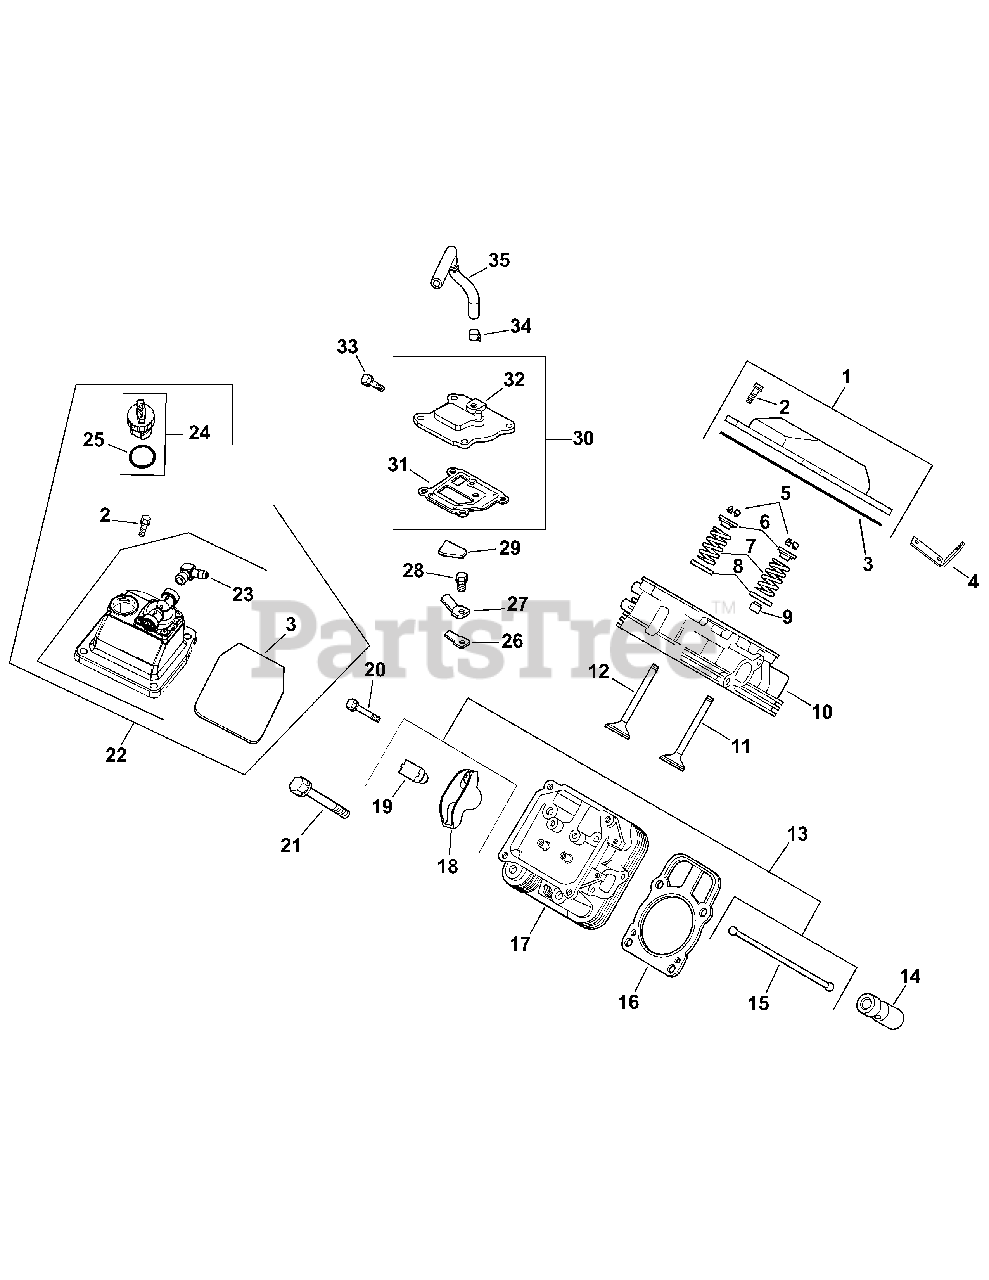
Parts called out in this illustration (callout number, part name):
1	Kit, valve cover - plain (Includes 2,3)
2	Screw, hex. flange M6x1.0x30 (4)
3	O-Ring, valve cover
4	Strap, lifting
5	Kit, retainer (4)
6	Cap, valve spring (4)
7	Spring, valve (4)
8	Retainer, spring (4)
9	Seal, valve stem (2)
10	Head assembly, #1 cylinder
11	Valve, intake (Std.) (2)
11	Valve, intake (.25) (2)
12	Valve, exhaust (Std.) (2)
12	Valve, exhaust (.25) (2)
13	Kit, valve train (Includes 15,18,19)
14	Lifter, valve (4)
15	Rod, push (4)
16	Kit, cylinder head gasket (Includes head mounting hardware)
17	Head assembly, #2 cylinder
18	Arm, rocker (4)
19	Pivot, rocker arm (4)
20	Screw, hex. flange M6x1.0x34 (4)
21	Screw, hex. flange M10x1.5x90 (8)
22	Kit, fuel pump valve (Includes 2,3,23-25)
23	Fitting, 90° (2)
24	Cap assembly, oil fill (Includes 25)
25	O-Ring
26	Reed, breather
27	Retainer, breather reed
28	Screw, hex. flange M5x0.8x10
29	Filter, breather
30	Kit, breather (Includes 31,32)
31	Gasket, breather
32	Cover, breather
33	Screw, hex. flange M6x1.0x20 (4)
34	Clamp, breather
35	Hose, breather
